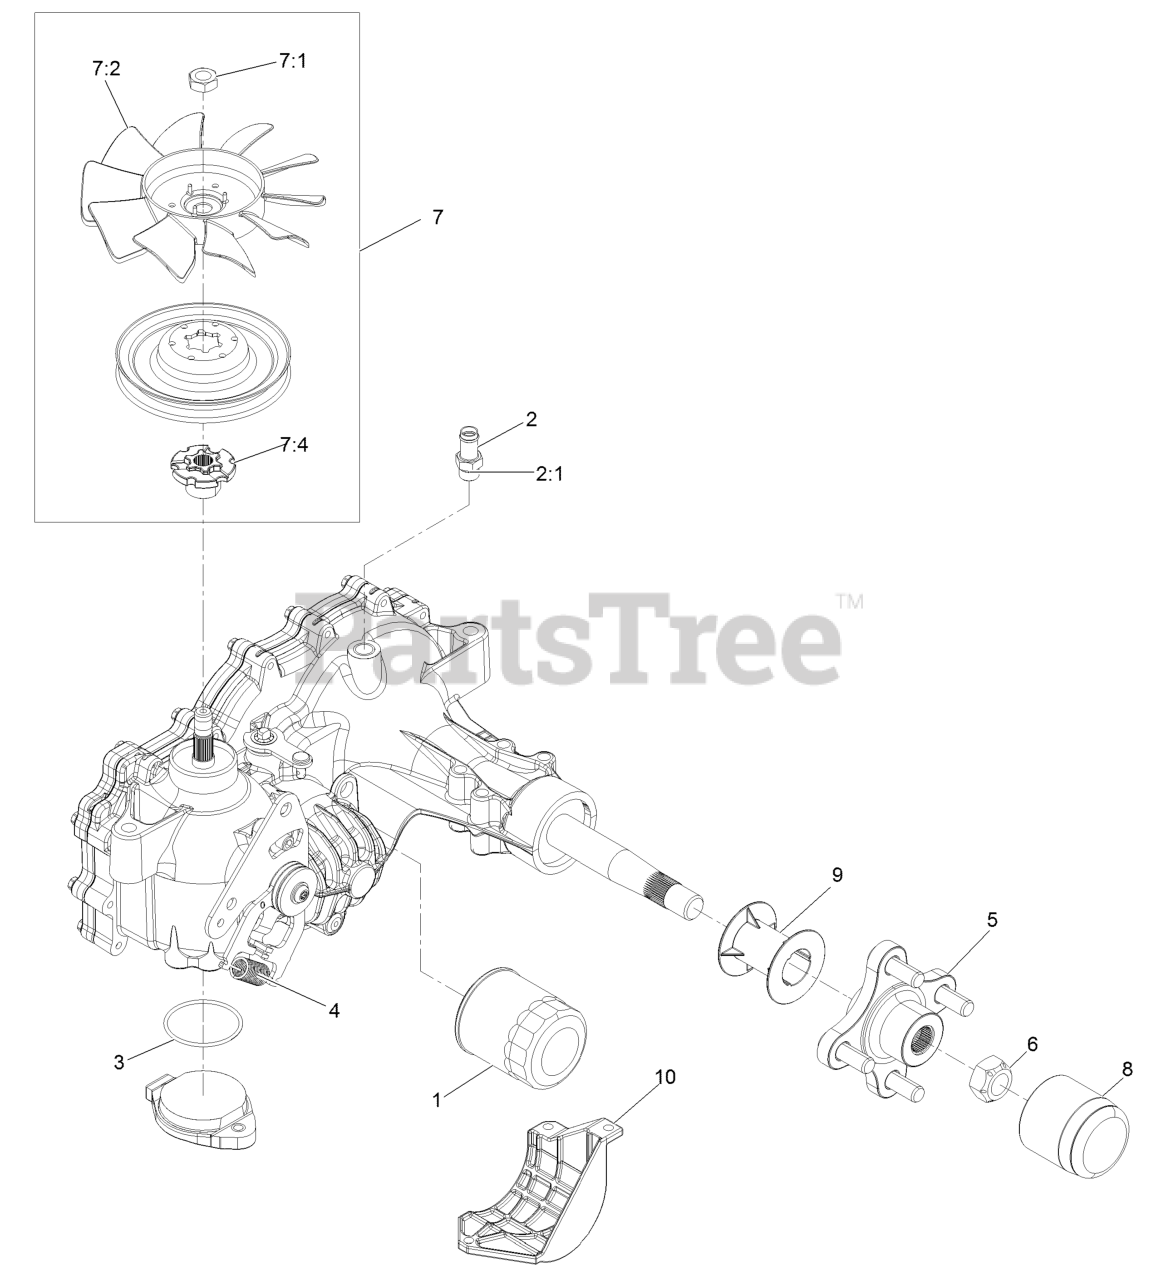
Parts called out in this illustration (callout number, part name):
1	Filter-Hydraulic
2	Adapter-Straight
2:1	O-Ring
3	O-Ring-Charge Seal Cover
5	Hub-Offset
6	Nut-Hub
7	Fan And Pulley Kit
7:4	Hub-Pulley
8	Cap-Long Axle
9	Tube-Axle
10	Guard-Filter, LH
99	Seal Kit
